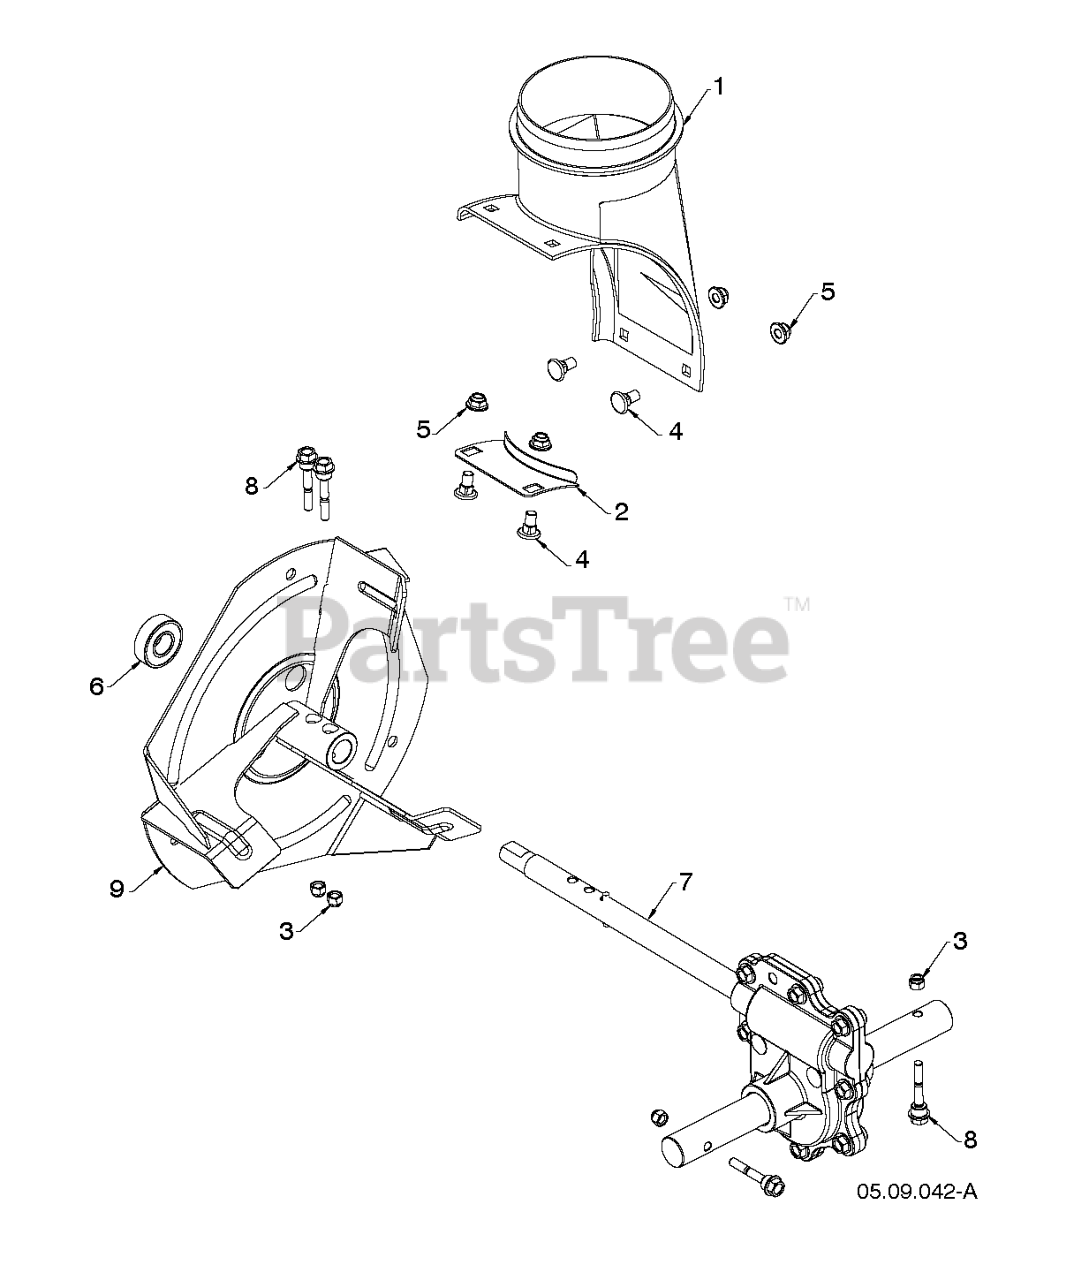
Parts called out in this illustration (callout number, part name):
1	CHUTE.DISCHARGE.BASE
2	BRACKET, CORNER DISCHARGE
3	Nut Lock, W/Insert 1/4 - 20 UNC (AYP part number)
4	BOLT CARR WAFER BLK 5_16-18 X
5	NUT HEX FLG NYLOCK BLK 5_16-1
7	TRANSMISSION.GEARBOX.ALUM.DD
8	BOLT.1/4-20 X 1-13/16 SHEAR
9	IMPELLER.STEEL.SNOW.BLACK
